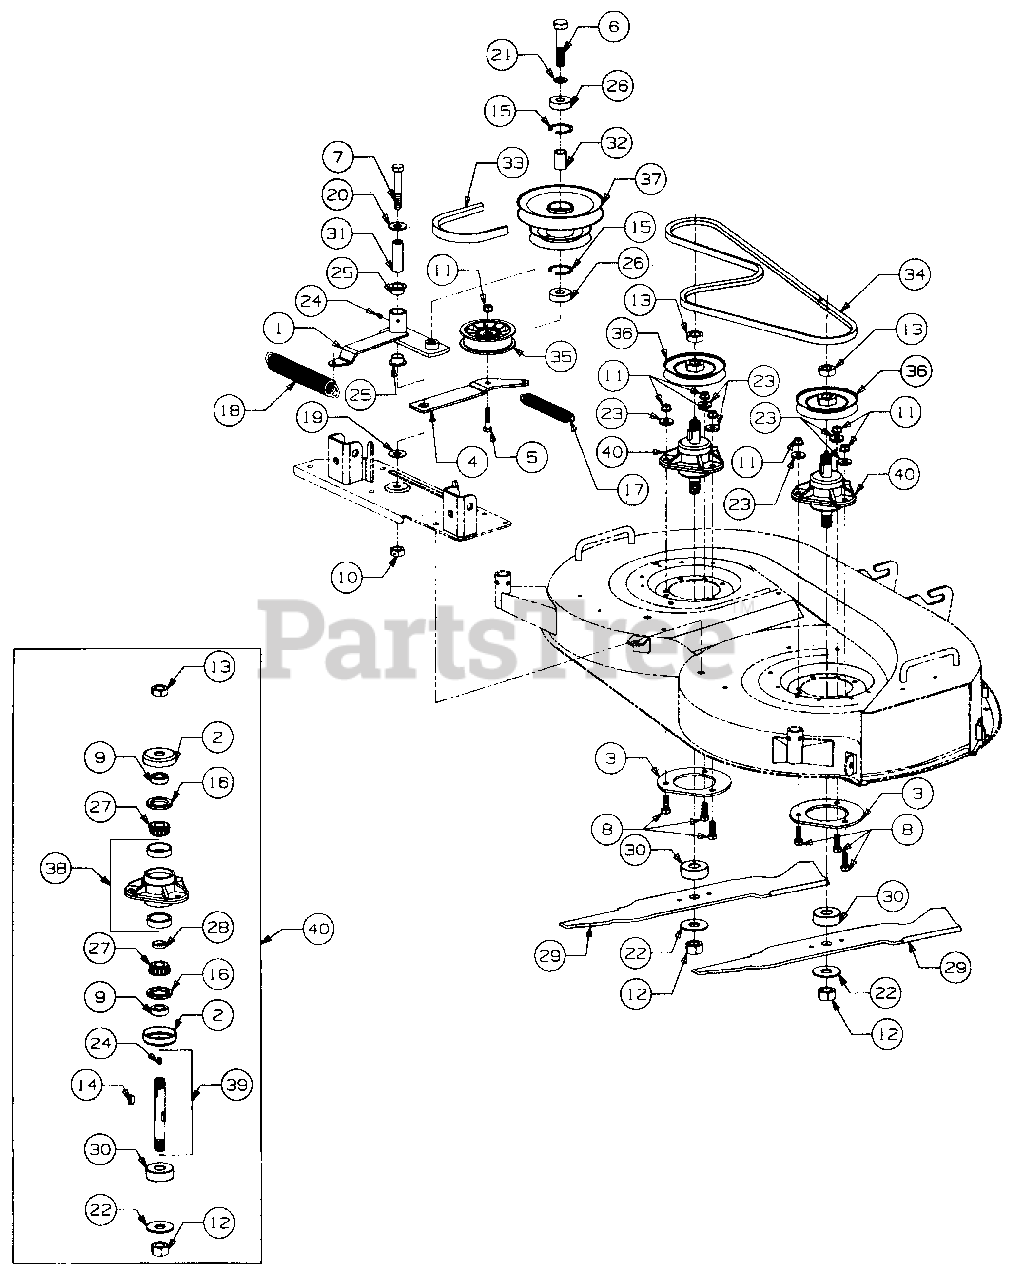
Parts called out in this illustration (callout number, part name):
2	Cup, Spindle Hdn
3	Plate, Spindle Mounting
5	Screw, Hex Cap 3/8-16 x 1.5 GR5
6	Screw, Hex Cap 5/8-18 x 3.0 GR5
7	Screw, Hex Cap 1/2-20 x 3.0 GR8
8	Screw, Hex Cap 3/8-16 x 1.25 GR5
9	Spacer, .755 x 1.25 x .44
10	Nut, Hex Center Lock, 1/2-20
11	Nut, Hex Flange Lock, 3/8-16
12	Nut, Hex, 3/4-16 GR8
13	Nut, Hex Jam, 3/4-16 GR5
14	Key, #91 Woodruff, 1/4 x 3/4 Hdn
15	Snap Ring, Internal
16	Seal, Oil, 1.25 x 1.874 x .25
17	Spring, Extension, .88 x 6.12
18	Spring, Extension, 1.25 x 8.15
19	Washer, Flat, .531 x 1.25 x .036
20	Washer, Flat, .531 x 1.25 x .100
21	Washer, Flat, .63 x 1.0 x .063 Hdn
22	Washer, Flat, .781 x 2.0 x .105
23	Washer, Flat, .385 x 1.0 x .135
24	Fitting, 3/16 Drive Lube
25	Bearing, Flange, 3/4 ID x .53 Lg
26	Bearing, Ball, .62 ID x 1.57 OD
27	Cone, Bearing
28	Spacer, Bearing
29	Blade, Low Lift, 21.20 Lg
30	Spacer
31	Spacer, Idler Brkt .50 ID x .75 OD x 2.25 Lg
32	Spacer, Pulley .635 ID x .88 OD x 1.25 Lg
33	Belt, PTO, B-Section x 112.4 Lg
34	Belt, Spindle, A-Section x 62 Lg
35	Pulley, Flat Idler, 3.5 OD
36	V-Pulley, 4.62 OD
37	Pulley, Double
38	Housing w/Cups, Spindle
39	Kit, Shaft w/Seal
40	Spindle Assembly, Blade
